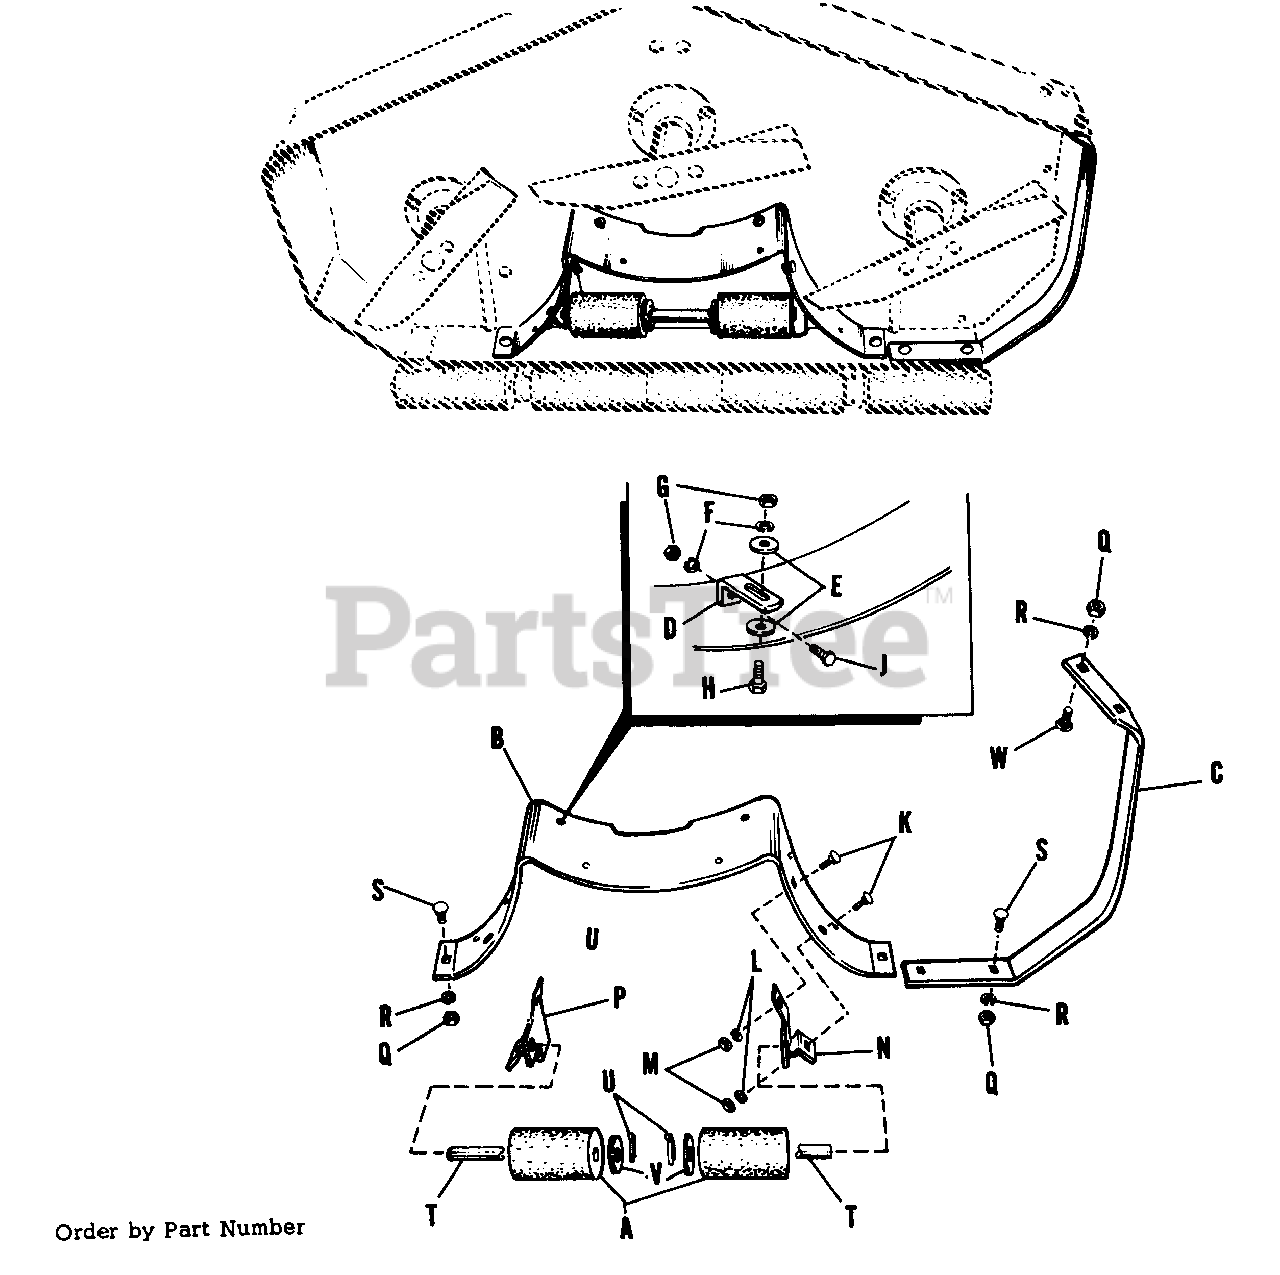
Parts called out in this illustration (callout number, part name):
C	Guard Assembly, Housing
D	Clip Baffle
E	Washer, Plain 1/4"
F	Washer, Lock 1/4"
G	Nut, Hex, Full, 1/4"-20 NC
H	Capscrew, Hex, 1/4"-20 x 5/8" lg.
J	Screw, Recessed Hex, Self-Tapping 1/4"-20 NC x 7/8" lg.
K	Bolt, Carriage, 5/16"-18 NC x 3/4" lg.
L	Washer, Lock, 5/16"
M	Nut, Hex, Full, 5/16"-18 NC
N	Bracket, Roller, Lower, L.H.
P	Bracket, Roller, Lower, R.H.
Q	Nut, Hex, Full, 3/8"-16 NC
R	Washer, Lock, 3/8"
S	Bolt, Carriage, 3/8"-16 NC x 3/4" lg.
T	Shaft, Roller
U	Pin, Cotter, 3/16" x 1" lg.
W	Bolt, Carriage, 3/8"-16 NC x 1" lg.
